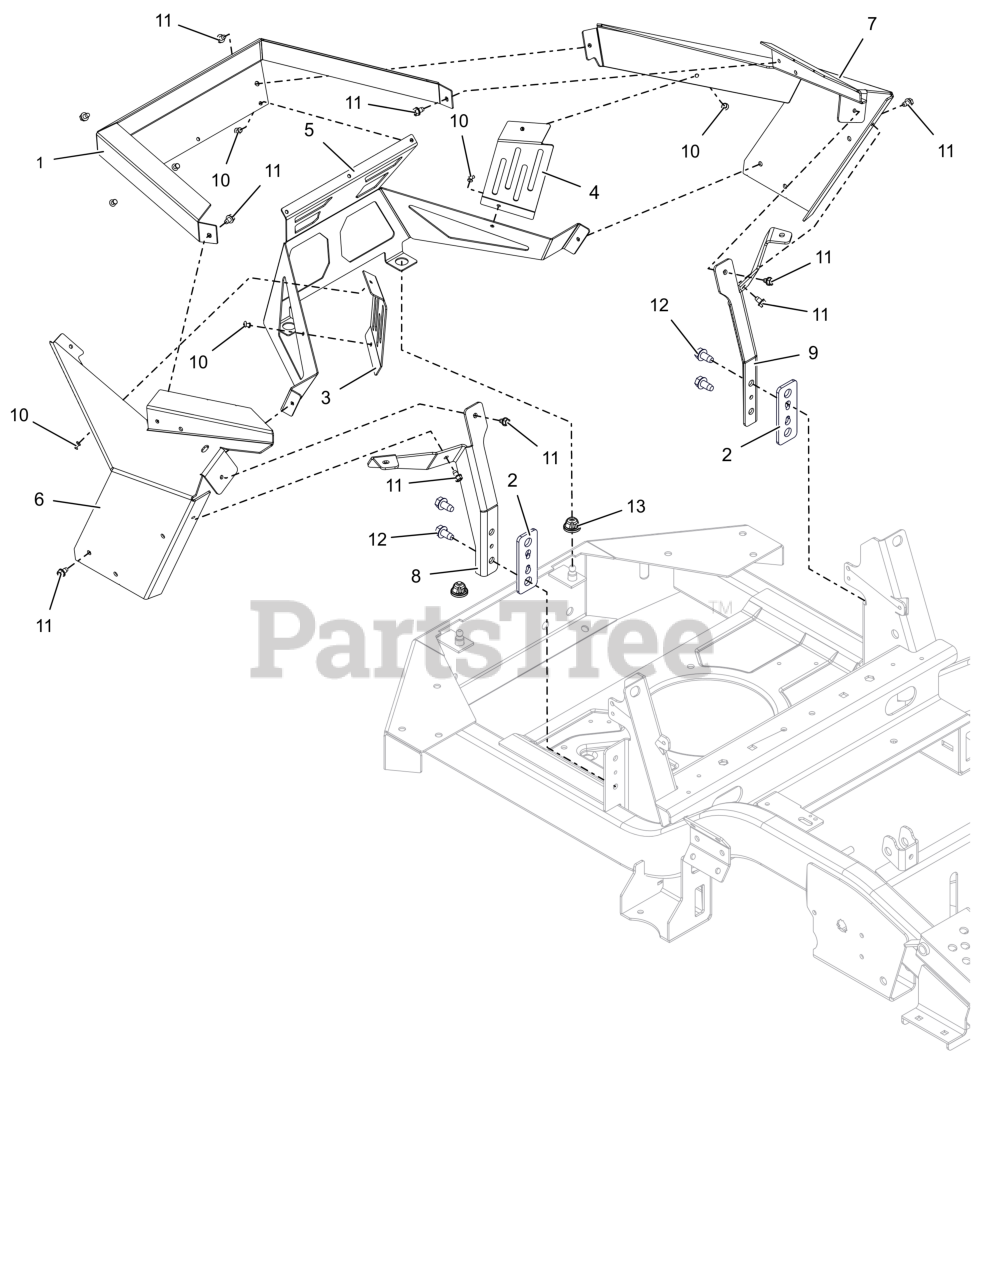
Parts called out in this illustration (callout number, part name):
1	GUARD,ENGINE WRAP
2	PLATE, CONTROL PANEL SPACER
3	SHIELD,RH ENGINE GUARD VALVE
4	SHIELD,LH ENGINE GUARD VALVE
5	GUARD, ENGINE
6	PANEL, RH REAR FENDER MOUNT
7	PANEL, LH REAR FENDER MOUNT
8	BRKT, RH FENDER MTG (ORANGE)
9	BRKT, LH FENDER MOUNT (ORANGE)
10	RVT-POP .187x.250 (#64) BLK
11	SCR,TAP .25-20X.375 HWH TR ZCC
12	SCR,TAP .375-16X.75 HWH TR ZCC
13	GROMMET, 10MM BOLLHOFF
